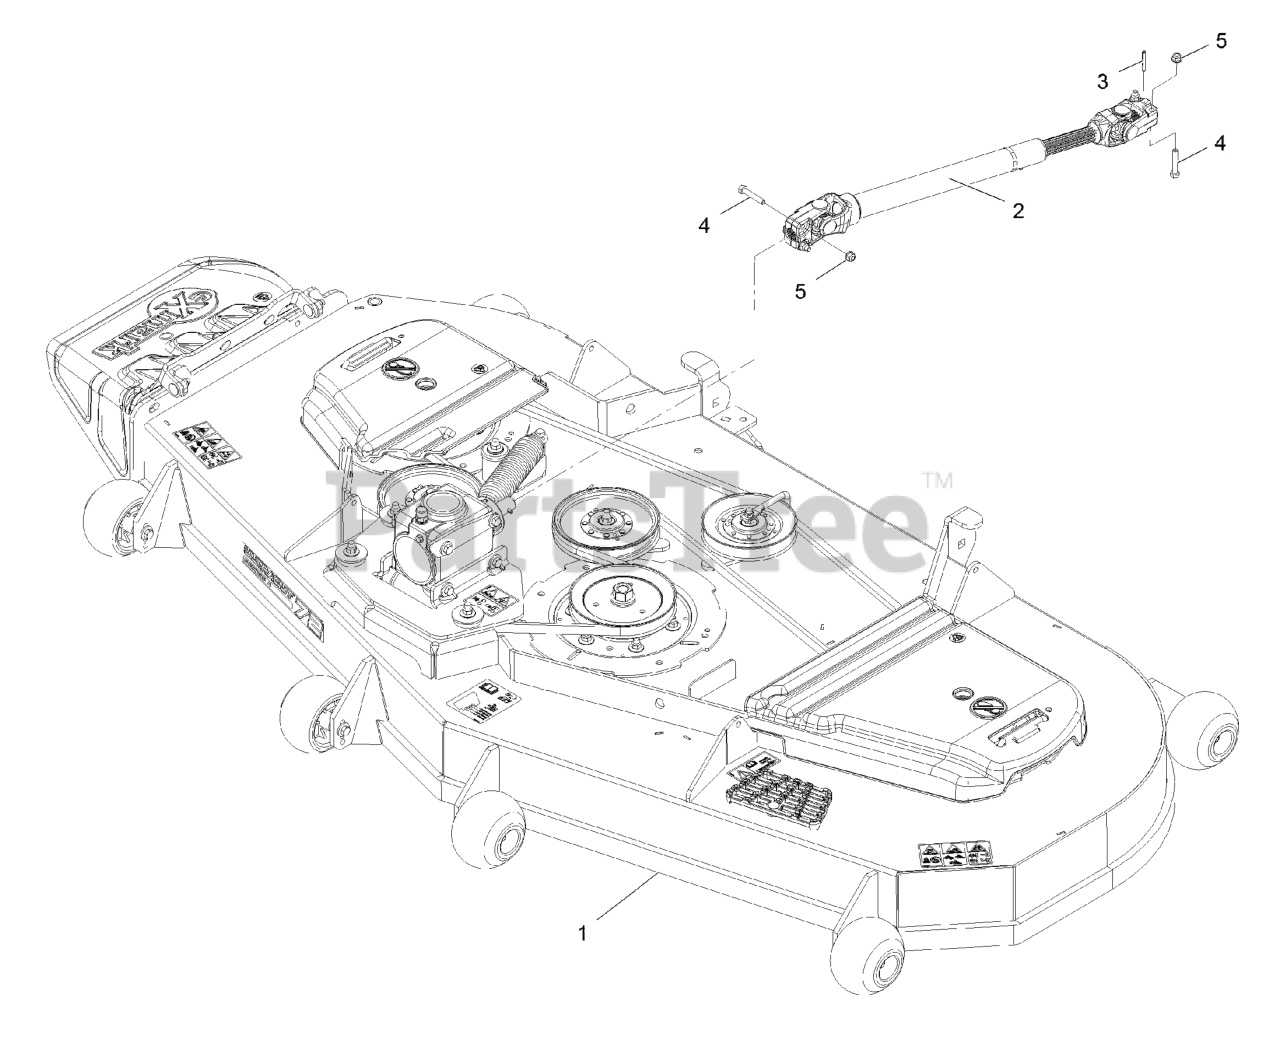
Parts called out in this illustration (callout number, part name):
1	Deck ASM-724
2	DRIVESHAFT ASM
3	PIN-ROLL
4	SCREW-HH
5	NUT-HF, NI
